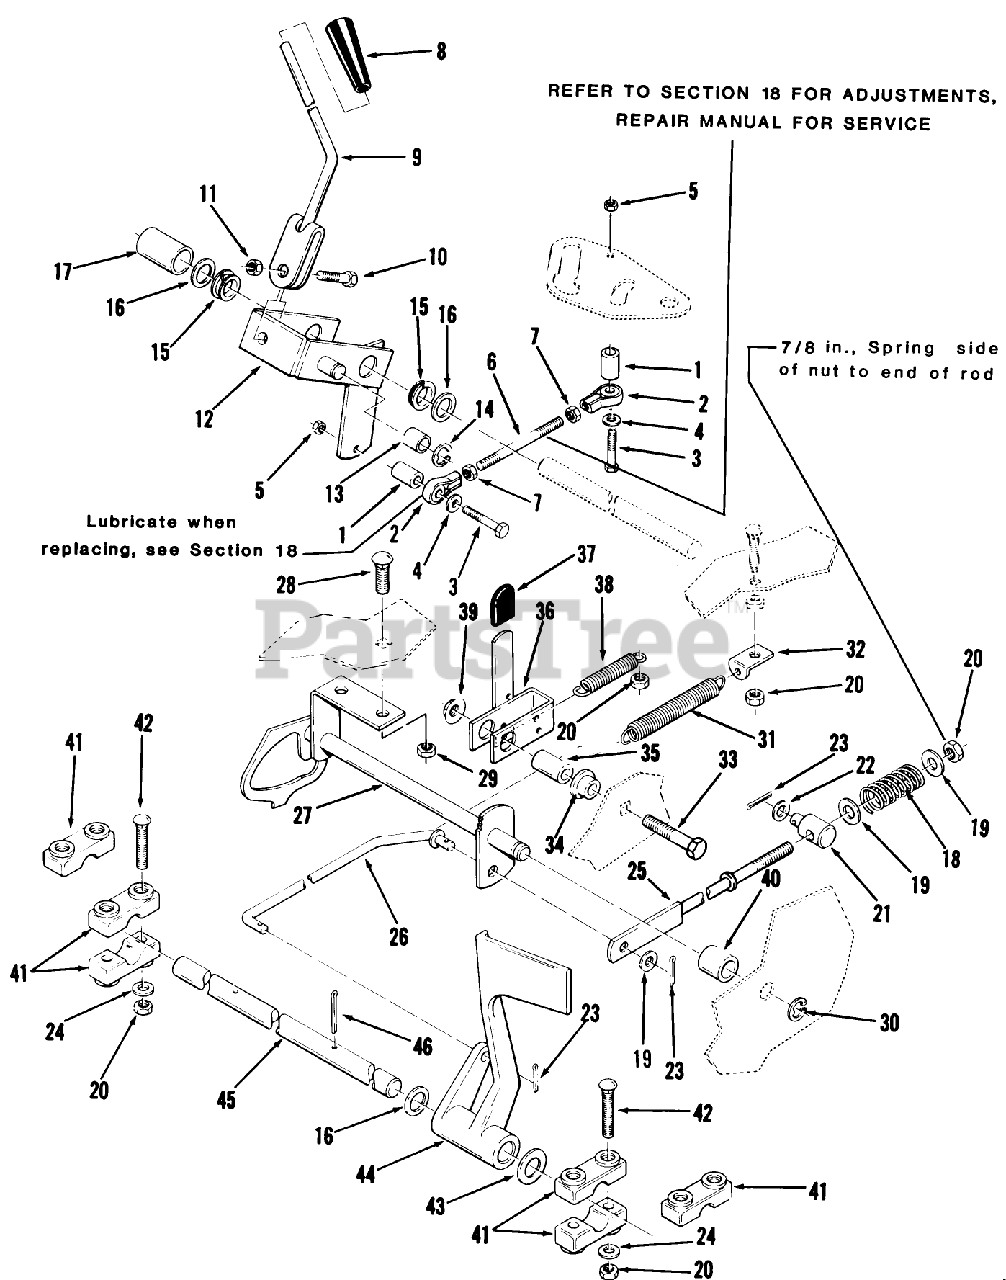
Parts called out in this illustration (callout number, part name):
1	BEARING CAM ROLLER
2	ASSY ROD END
8	KNOB
13	BEARING-CAM RETURN
21	TRUNNION-LIFT
24	WASHER 5/16 SAE
32	CLIP - SPRING
34	SPACER
35	SPACER
37	GRIP
38	SPRING-EXTENSION
43	Special Washer
44	PEDAL CLUTCH *R
